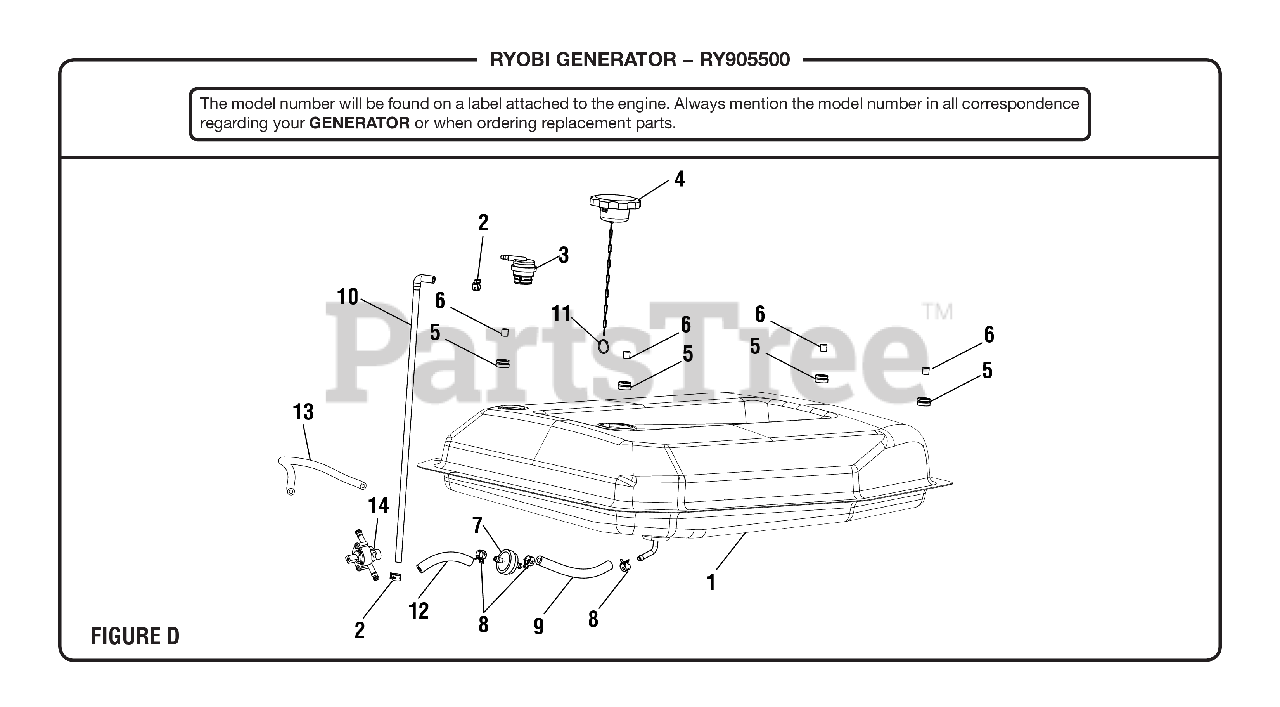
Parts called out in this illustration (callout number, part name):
1	Fuel Tank Assembly (See Fig. B)
2	Fuel Line Clamp (7/16 in., BM903611)
3	Fuel Tank Vapor Vent
4	Fuel Cap Assembly
5	Bushing (Fuel Tank Isolator)
6	Spacer (Fuel Tank Isolator)
7	Fuel Filter Inline (1/4 in.)
8	Fuel Line Clamp (1/2 in.).
9	Fuel Hose (175 mm)
10	Vapor Hose
11	Ring Clip
12	Fuel Hose (85 mm)
13	Fuel Hose (330 mm)
14	Fuel Valve
